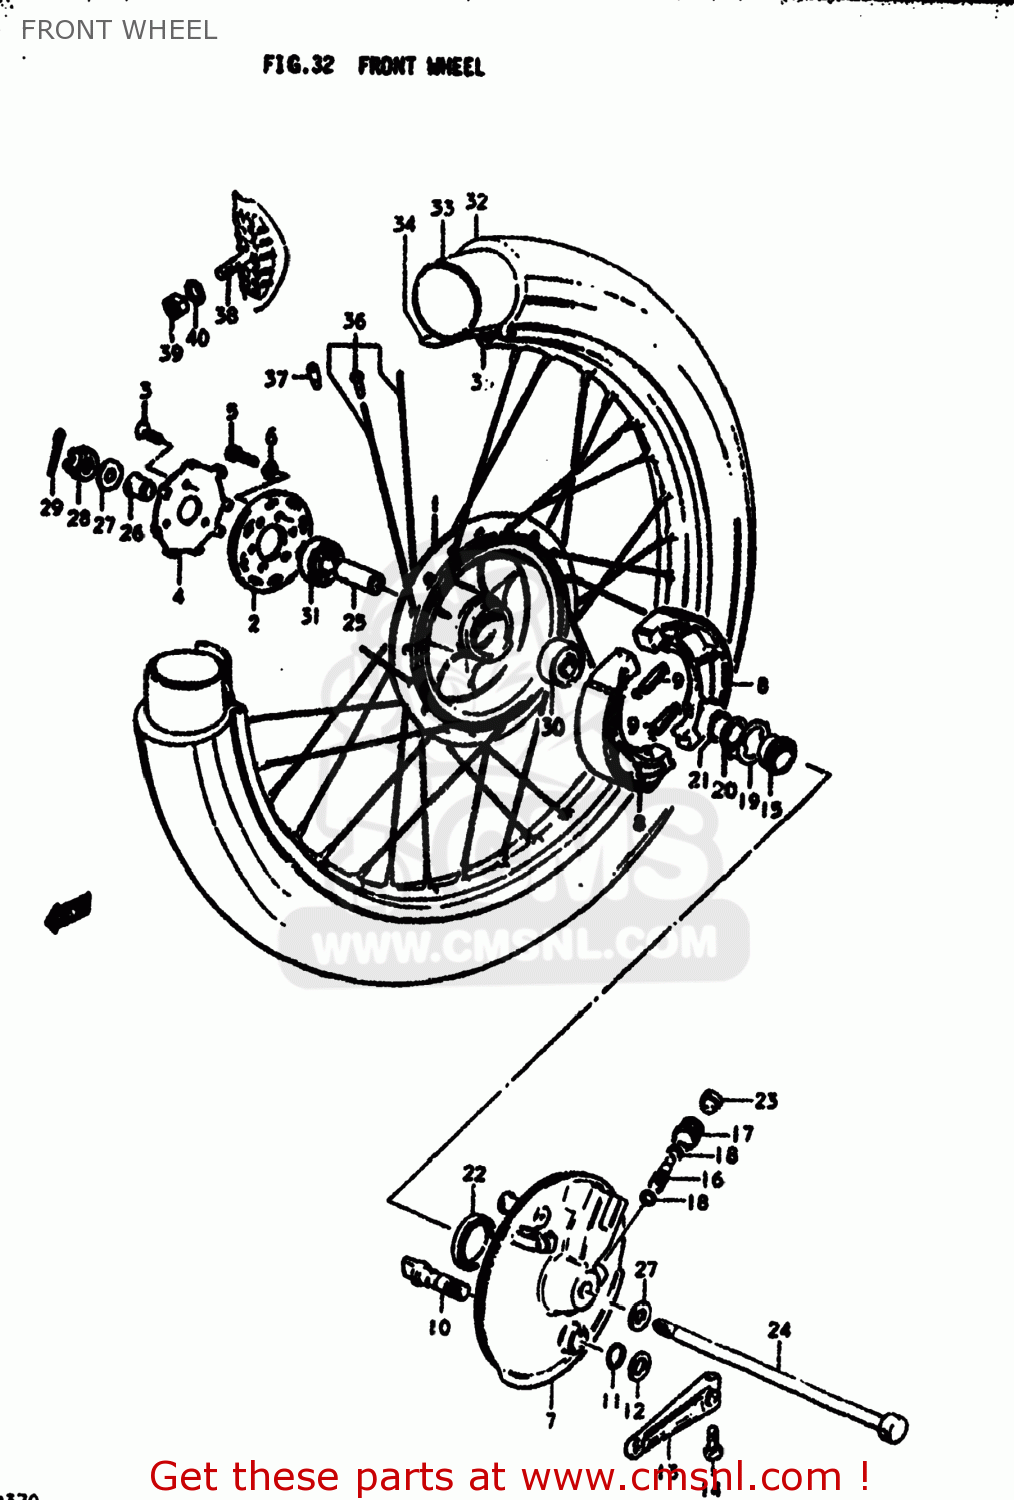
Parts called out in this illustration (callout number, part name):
1	DRUM,FRONT HUB
2	FLANGE,FR HUB,R
3	SCREW
4	RETAINER,FR HUB BEARING,R
5	BOLT, UPPER
6	LOCK WASHER
7	PANEL,FRONT HUB
8	SHOE,BRAKE (MCA)
9	SPRING
10	CAM,FRONT BRAKE
11	O-RING,BOSS
12	WASHER (15X24X1.6)
13	LEVER,FRONT BRAKE CAM
14	BOLT
15	GEAR,SPEEDOMETER
16	PINION,SPEEDOMETER
17	BUSHING,SPEEDOMETER PINION
18	WASHER (5.1X9X0.4)
19	DRIVER,SPEEDOMETER GEAR
20	WASHER(22.5X27X1)
21	CIRCLIP
22	SEAL,OIL(26X38X4)
23	SEAL,OIL(6X10X3)
24	AXLE,REAR
25	SPACER (12.6X19X52)
26	SPACER,FR AXLE,R
27	WASHER
28	NUT, REAR AXLE
29	COTTER PIN
30	BEARING
31	BEARING, RH
32	TIRE,FRONT
33	TUBE
34	PROTECTOR,WHEEL,INNER
35	RIM,FRONT WHEEL
36	SPOKE SET,FRONT
37	BALANCER,WHEEL (50G)
38	STOPPER,BEAD
39	NUT
40	WASHER
